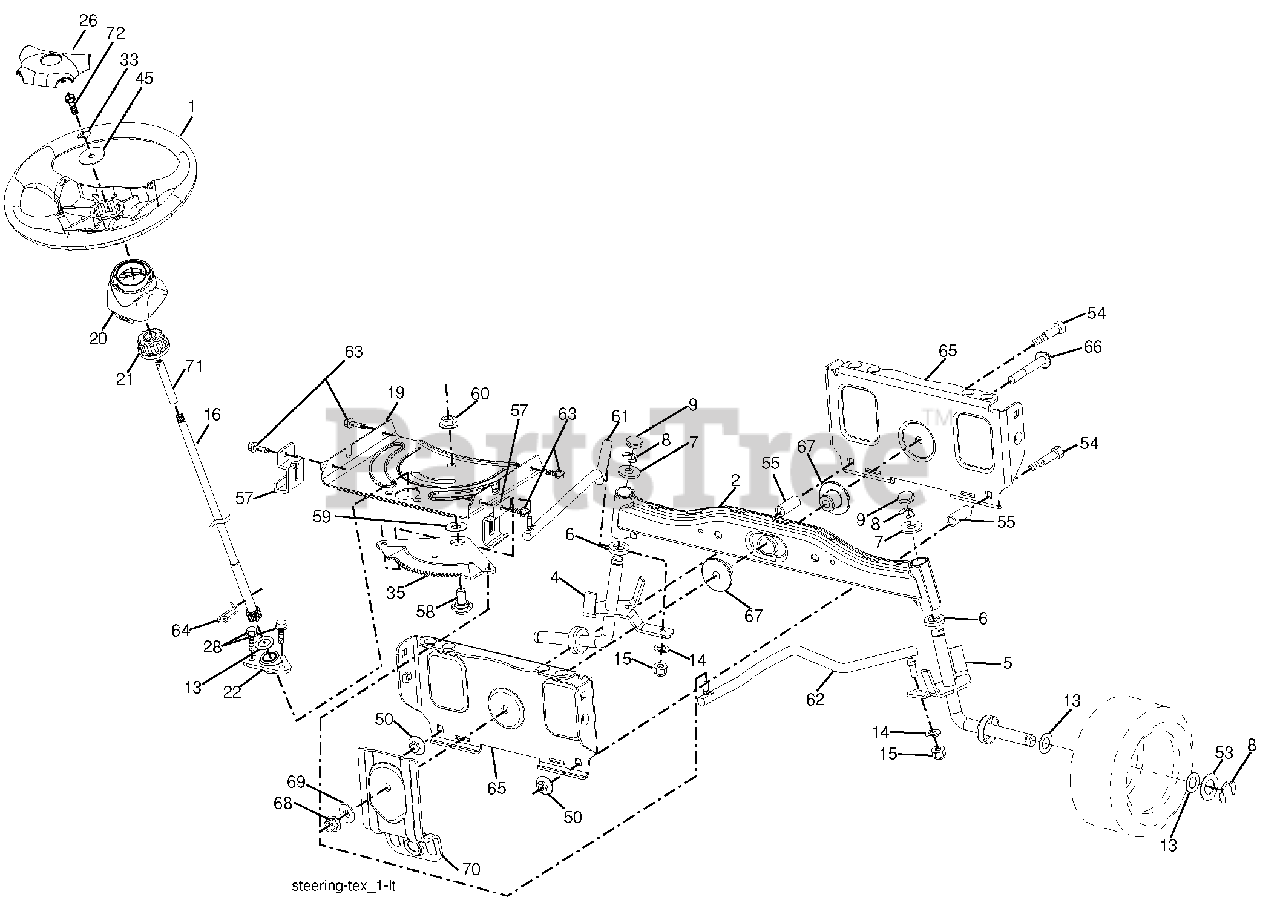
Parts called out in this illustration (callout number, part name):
1	Wheel, Steering
2	Axle Asm., Front
4	Spindle Asm., LH
5	Spindle Asm., RH
6	Bearing, Race Thrust Harden
7	Washer 25/32 x 1-5/8 x 16 Ga.
8	Ring, Klip #T5304-75
9	Cap, Spindle
13	Washer 25/32 x 1-1/4 x 16 Ga.
14	Washer Lock 3/8
15	Nut, Crown Lock 3/8-24 unf
16	Shaft Steering
19	Plate Steering
20	Boot, Steering
21	Adapter, Wheel Steering
22	Bushing, Strg. Blk
26	Insert, Wheel Steering
28	Screw 3/8-16 x 3/4
33	Washer Lock 5/16
35	Gear, Sector Plate
45	Washer 11/32 x 2-3/8 x 12 Ga.
50	Nut Lock Flg 3/8-16 unc
53	Washer Hardened .793 x 1.637 x .060
54	Bolt Hex HS 3/8-16 unc x 2-1/4
55	Spacer Brace Axle
57	Bracket Upstop
58	Bolt Shoulder Sector Pivot CFM
59	Washer Thrust Sector Steering
60	Nut Flange Lock 5/8-11
61	Draglink, LH
62	Draglink, RH
63	Screw 5/16-18 x 3/4
64	Retainer Clip Spring Steering
65	Brace Axle Front
66	Bolt Hex Fghd 7/16-14 x 3 Serr
67	Bushing PM Front Axle
68	Nut Lock Flange 7/16-14 Gr. 5
69	Washer 1.5 x .505 x .118
70	Bracket Deck Susp. Front
71	Shaft Ext. Steering
72	Bolt 5/16-18 x 4.5 Gr. 5
